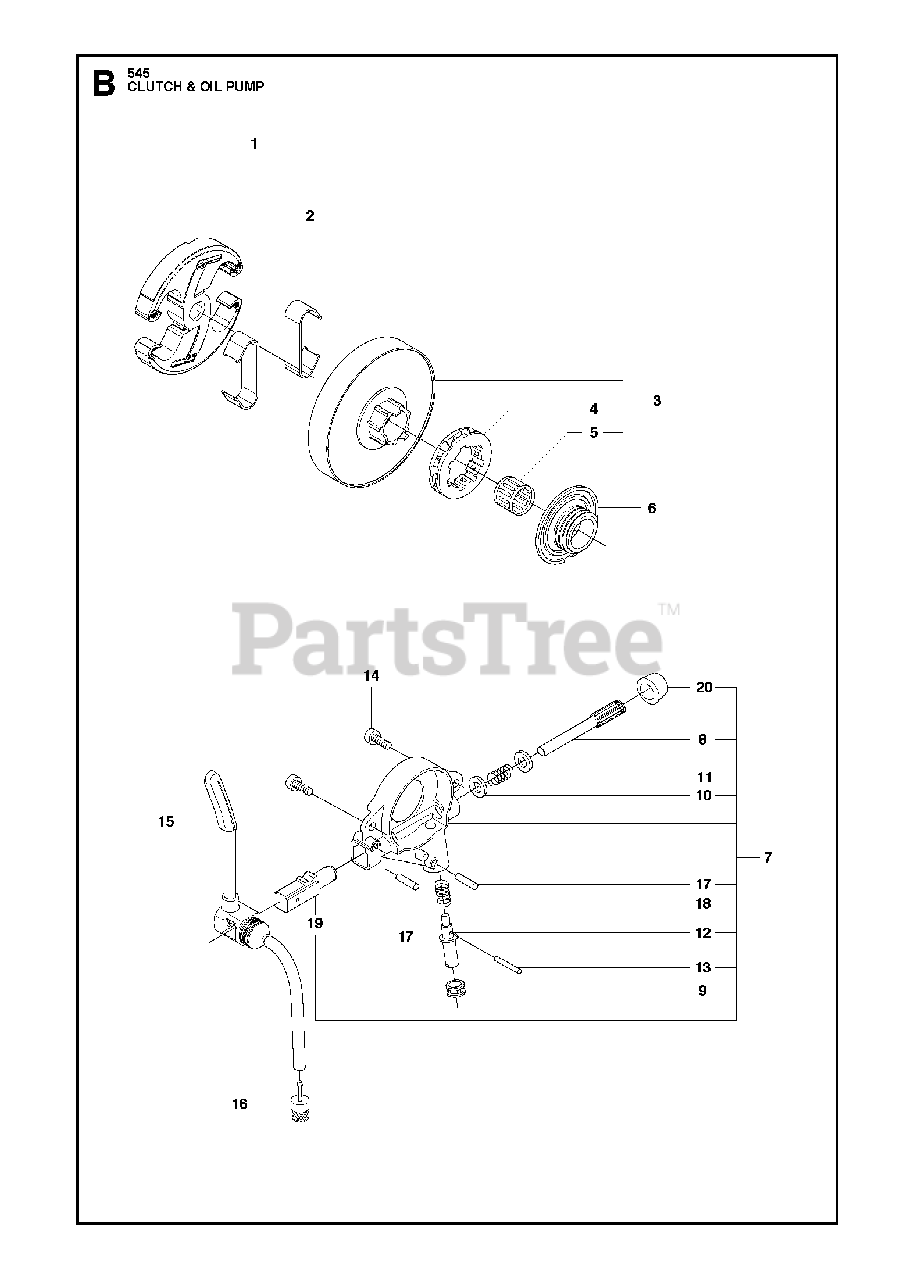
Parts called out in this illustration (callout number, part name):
1	CLUTCH ASSY
2	SPRING
3	CLUTCH DRUM ASSY
4	RIM SPROCKET 7T .325
5	SUPPORT BUSHING
6	WORM WHEEL
7	OIL PUMP ASSY
8	PUMP PISTON
9	CASING
10	WASHER
11	SPRING
12	RP ADJUSTING SCREW
13	PIN
14	SCREW IHSCM
16	OIL PLUMMET
17	PIN 3X10
18	SPRING
19	PUMP CYLINDER
20	PLUG
